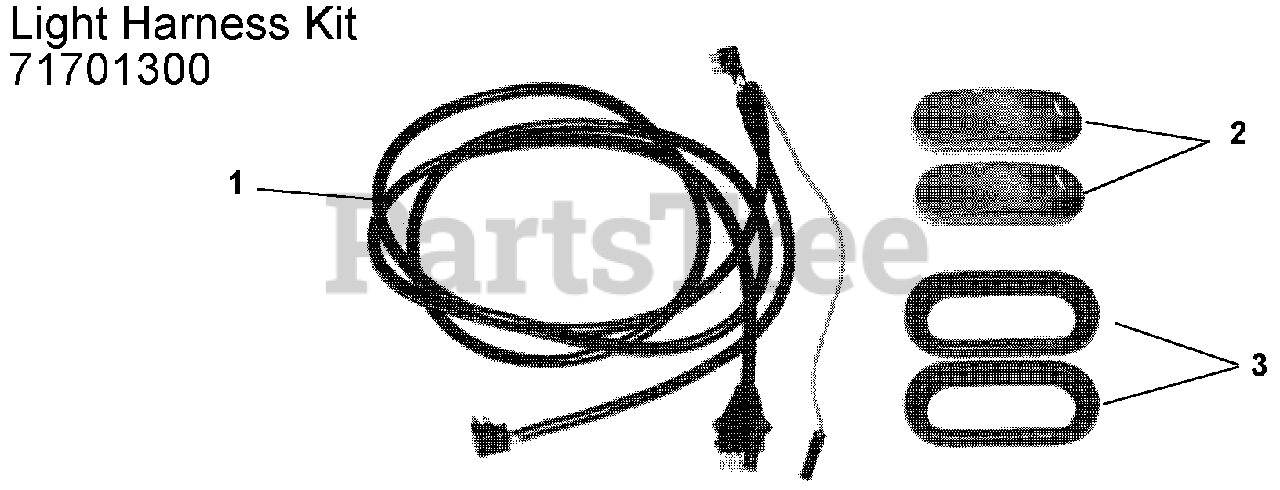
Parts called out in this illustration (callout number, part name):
1	WIRE HRNS,TRAILER LIGHT KIT
2	TAIL LIGHT HOUSING W/ BULB
3	GROMMET, TAIL LIGHT MOUNTING
